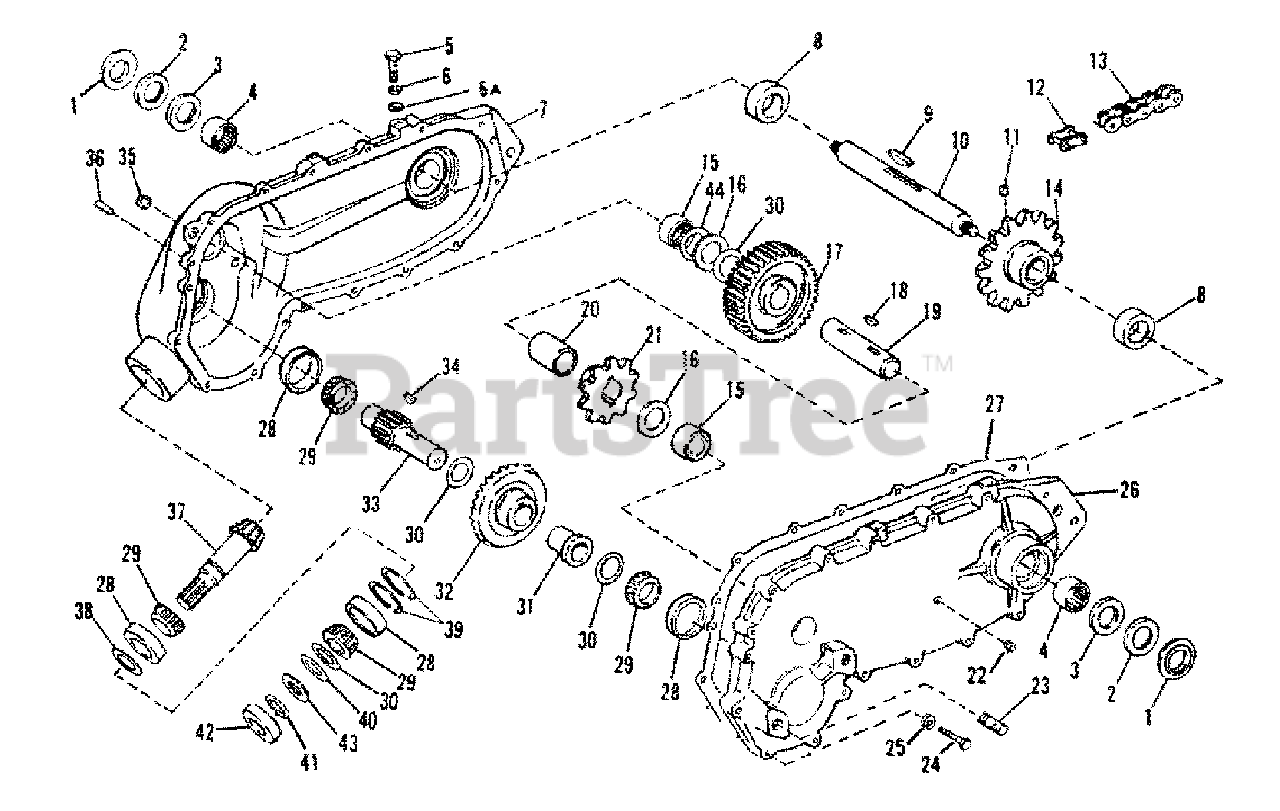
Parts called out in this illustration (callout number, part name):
1	Seal Washer
2	Oil Seal
3	Oil Seal
4	Needle Bearing
5	Hex Head Capscrew, 1/2-13 x 1-1/4
6	Lockwasher, 1/2
7	Tiller Case
8	Thrust Washer
9	Hi-Pro Key, 5/16 x 2
10	Tine Shaft
11	Set Screw, 3/8-16 x 1/2
12	Connector, Roller Chain
13	Roller Chain, 1 Pitch
14	Sprocket, 15 Tooth 1" Pitch
15	Needle Bearing
16	Thrust Washer
17	Gear, 39 Tooth
18	Key, 5/16 x 1-1/16
19	Shaft
20	Spacer
21	Sprocket, 10 Tooth 1" Pitch
22	Pipe Plug, 1/8 NPT
24	Capscrew, 5/16-18 x 2-1/4
25	Lockwasher, 5/16
26	Gear Case Cover
27	Gasket
28	Bearing Cup
29	Bearing Cone
30	Shim, .005
31	Spacer
32	Bevel Gear, 40 Tooth
33	Pinion and Shaft
34	Woodruff Key, 1/4 x 1
35	Pipe Plug
36	Drive Pin
37	Pinion, 13 Tooth
38	Shim, .005
39	Retaining Ring
40	Thrust Race
41	Retaining Ring
42	Oil Seal
43	Thrust Race
44	Shim, .020
